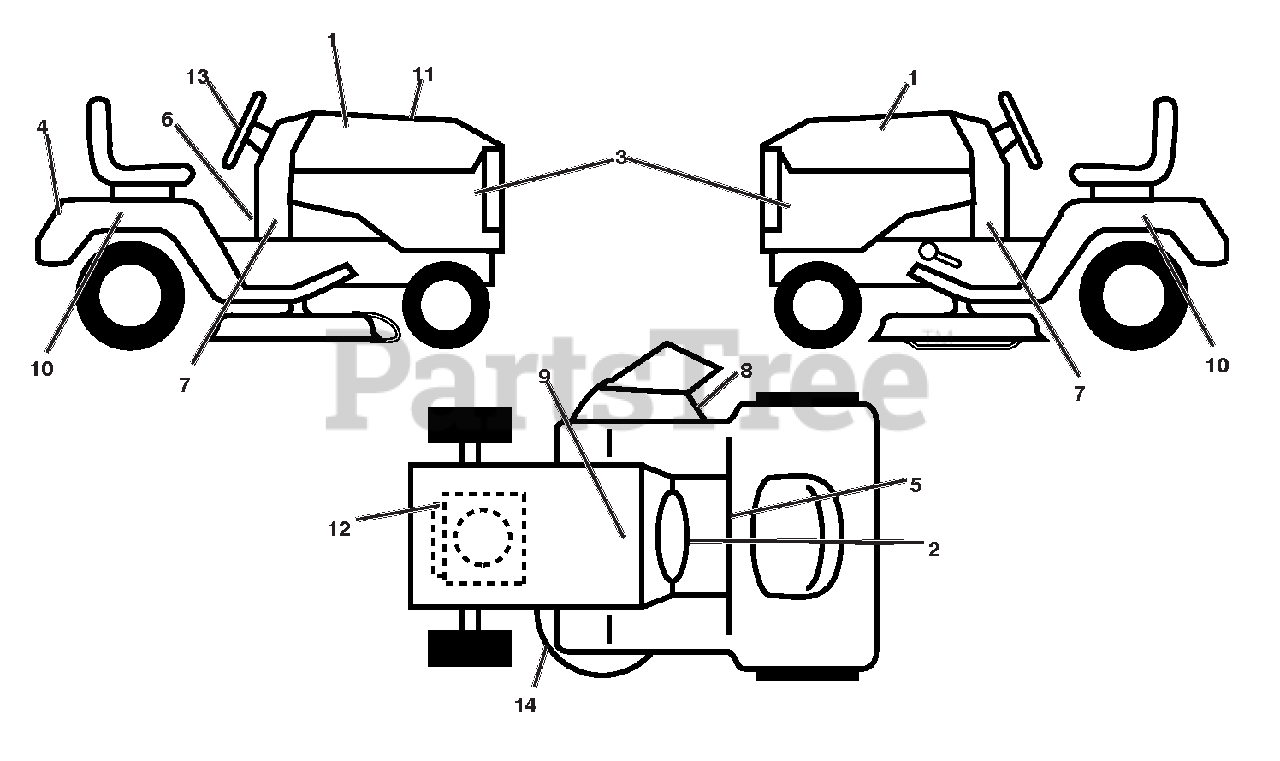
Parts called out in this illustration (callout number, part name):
1	DECAL.HOOD.LH/RH.
2	DECAL.WARNING.START
3	DECAL.SDPNL.PWRDBY B&S.ARIENS
4	DECAL.FENDER.REAR.ARIENS
5	DECAL.FENDER
6	DECAL.WARNING SPARK
7	DECAL.DASH TOWER
8	DECAL.WARNING.KEEP.HAND.AWY
9	DECAL.BAT.DAN/POI P/L SYM.WPN
10	DECAL, FENDER
11	DECAL.REPLACEMENT
12	DECAL.ENGINE H.P.
13	DECAL.WHEEL.STEER.ARIENS
14	DECAL.V-BELT.SCH.
